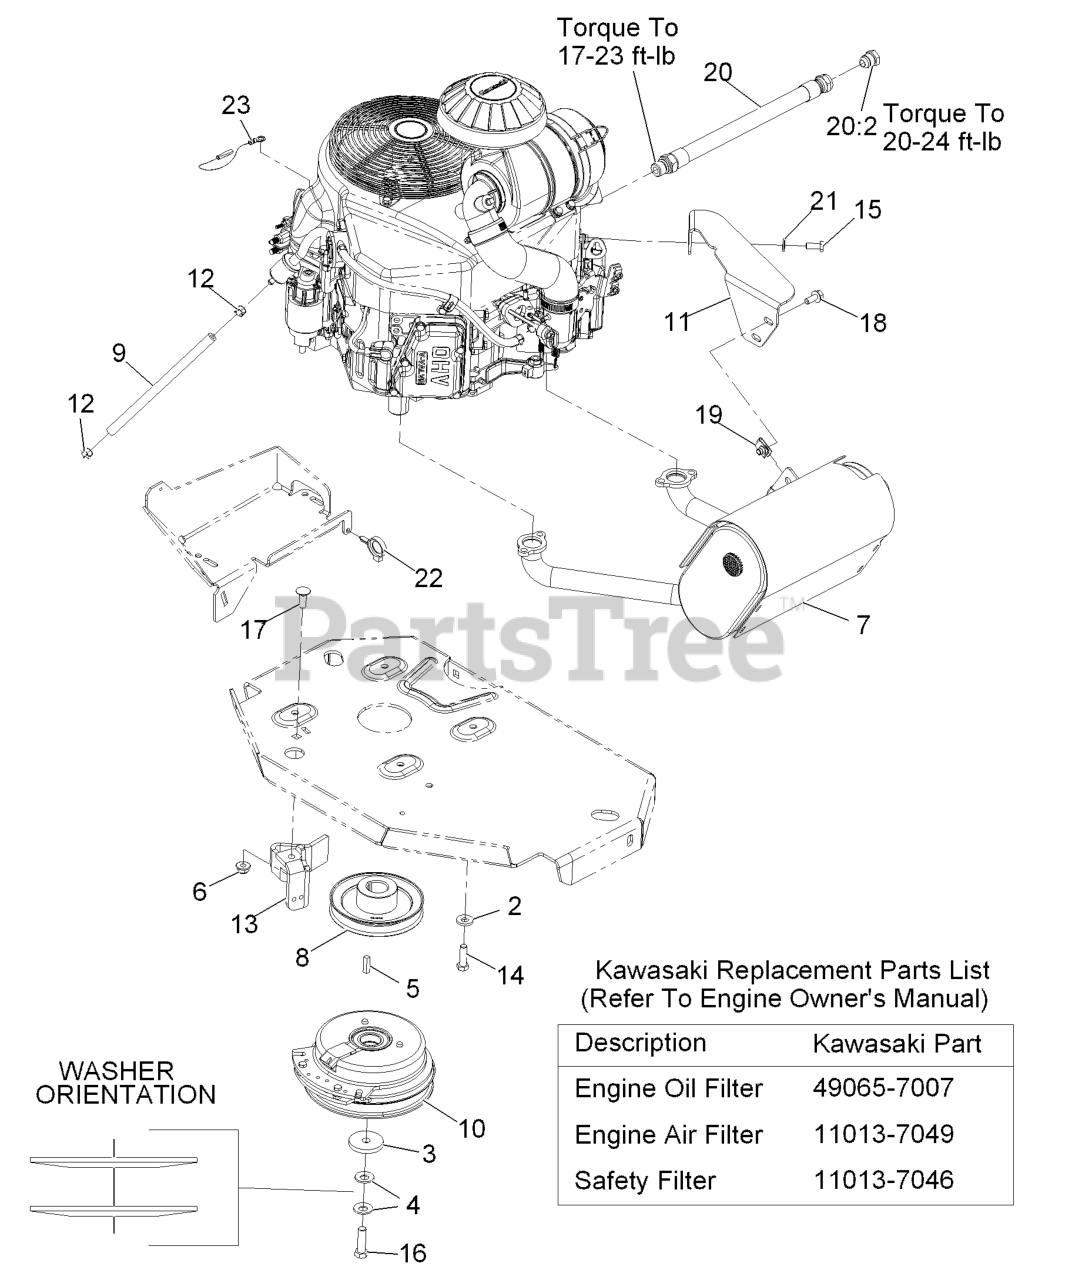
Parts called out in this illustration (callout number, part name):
2	WASHER-BELLEVILLE
3	WASHER-CLUTCH
4	WASHER-SPRING
6	NUT-HF, NI
7	MUFFLER
8	SHEAVE-PUMP, DRIVE
9	HOSE-FUEL
11	BRACKET-MUFFLER
12	CLAMP-HOSE
13	CLUTCH-ANCHOR
14	SCREW-HH
15	SCREW-HH
16	SCREW-HH 7/16-20 X 1 1/2 W/LOCTITE
17	SCREW-CARR
18	SCREW-HHF
20	ENGINE OIL DRAIN HOSE ASM
20:2	PLUG-HH
21	WASHER-SPRING
22	CLAMP-HOSE
23	HARNESS-GROUND, SOLENOID
